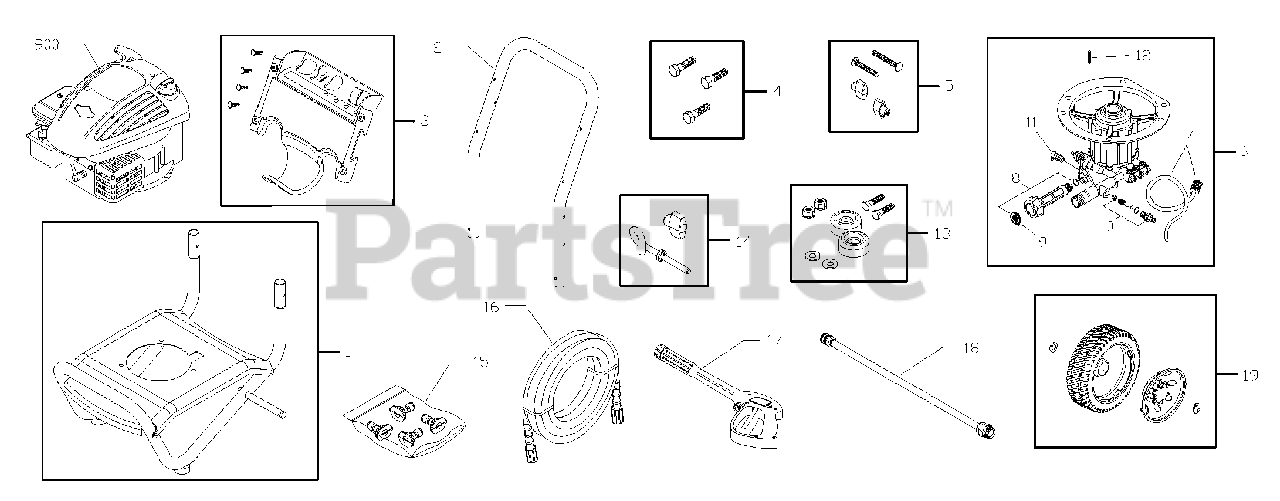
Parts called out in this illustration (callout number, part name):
4	KIT, Hardware, Pump Mounting
5	KIT, Hardware, Handle
7	KIT, Chemical Hose
8	KIT, Water Inlet
9	FILTER, Garden Hose
10	KIT, Chemical Injection
11	VALVE, Thermo Relief
13	MOUNT, Vibration
15	KIT, QC Nozzles
16	HOSE
17	GUN
18	EXTENSION, QC
900	* ENGINE
